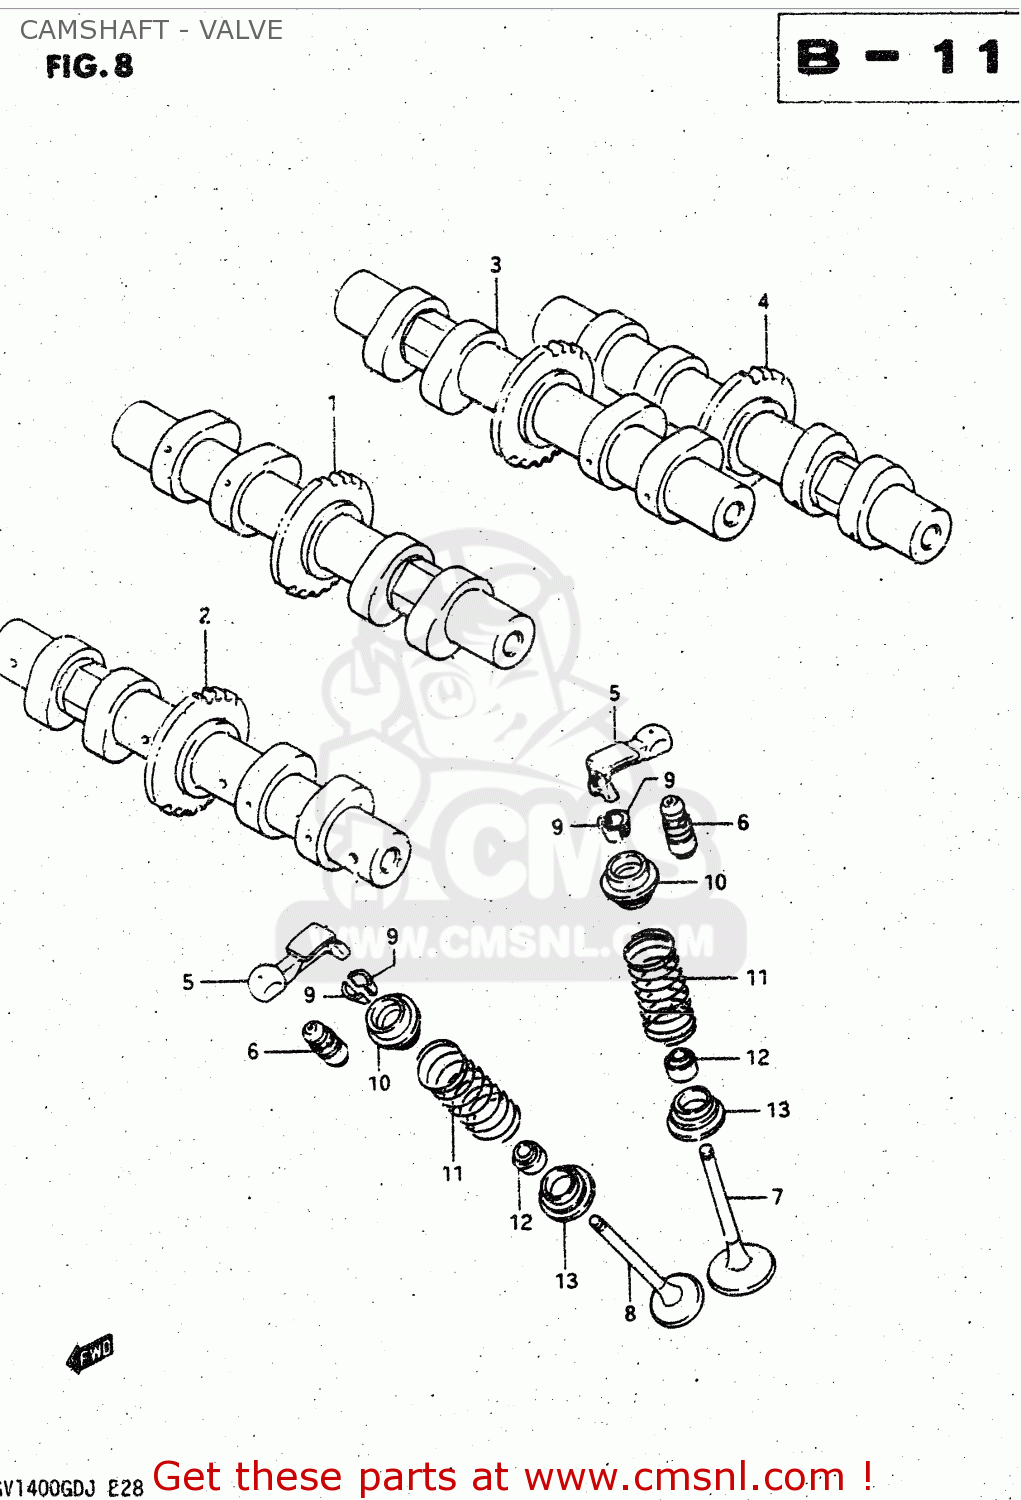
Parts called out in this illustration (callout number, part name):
1	SHAFT COMP,INTAKE FRONT CAM
2	SHAFT,EXHAUST FRONT CAM
3	SHAFT COMP,INTAKE REAR CAM
4	SHAFT,EXHAUST REAR CAM
5	ARM,VALVE ROCKER
6	ADJUSTER,HYDRAULIC VALVE
7	VALVE,INTAKE
8	VALVE,EXHAUST
9	COTTER VALVE
10	RETAINER,VALVE SPRING
11	SPRING,VALVE
12	SEAL,OIL(5X10.5X8.4)
13	SEAT,VALVE SPRING
